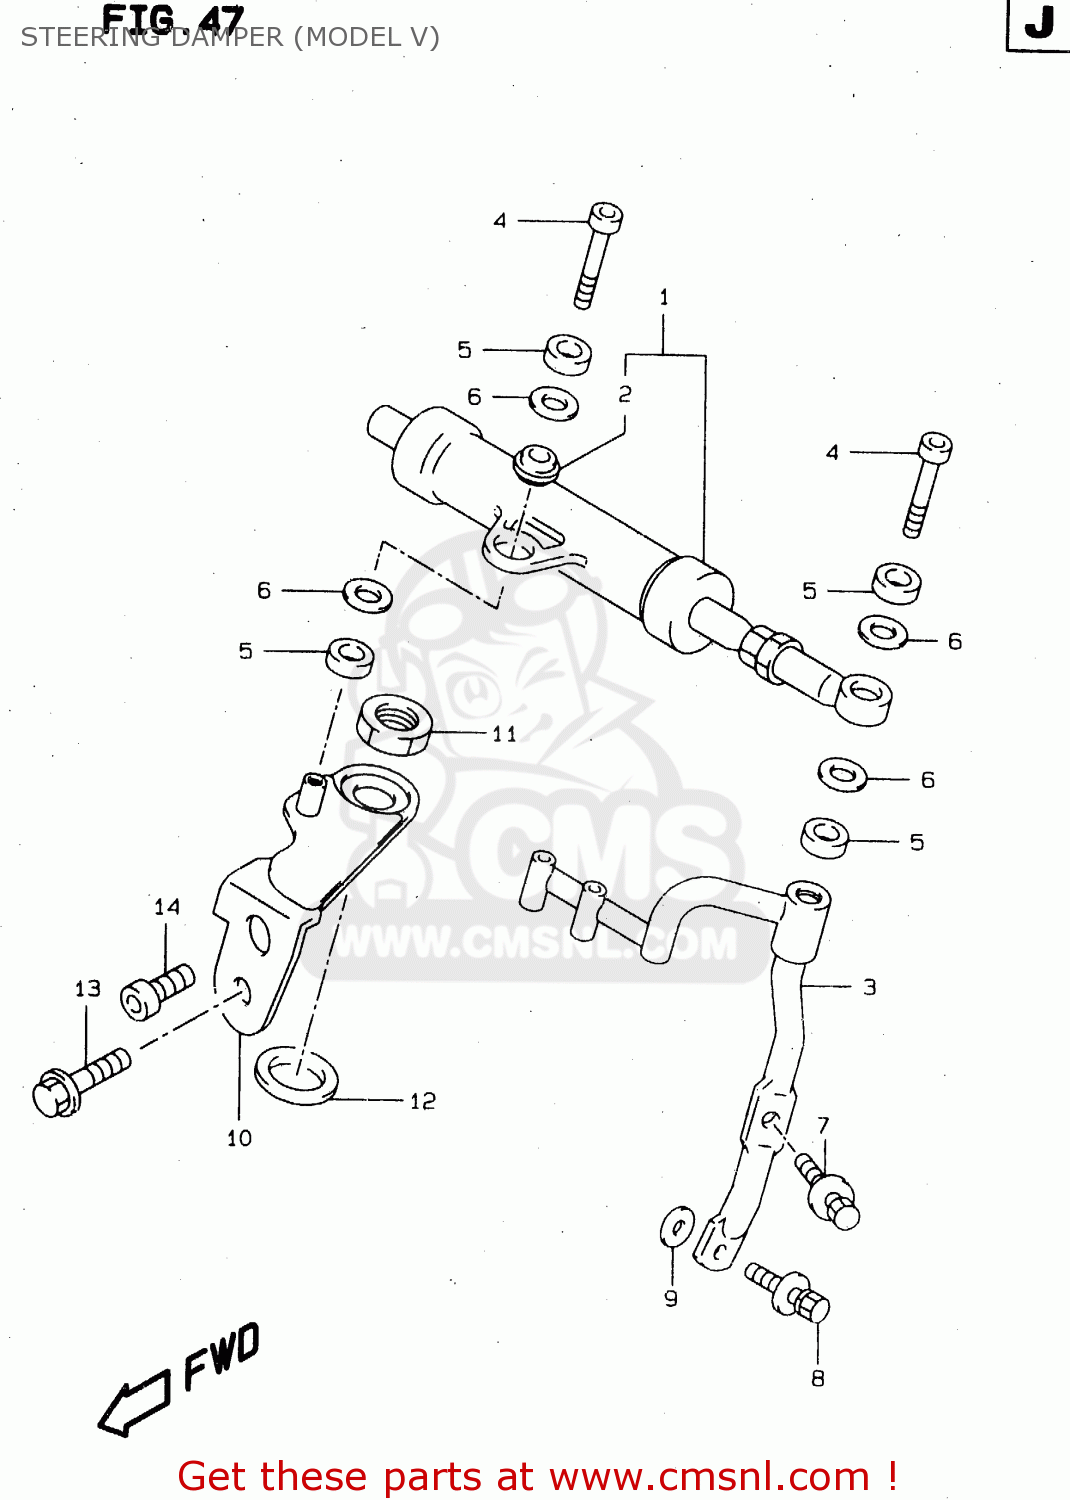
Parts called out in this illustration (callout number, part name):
1	DAMPER ASSY, STEERING
2	BEARING(8X17.5X11)
3	STAY,STEERING DAMPER
4	BOLT(8X35)
5	6
6	SHIM(8X12X0.8)
7	BOLT(6X30)
8	BOLT,STAY,LOWER 6X35
9	WASHER(6.5X20X1.6)
10	PLATE,STEERING DAMPER
11	NUT,STEM TOP
12	WASHER,STEERING DAMPER
13	BOLT
14	BOLT(8X32)
